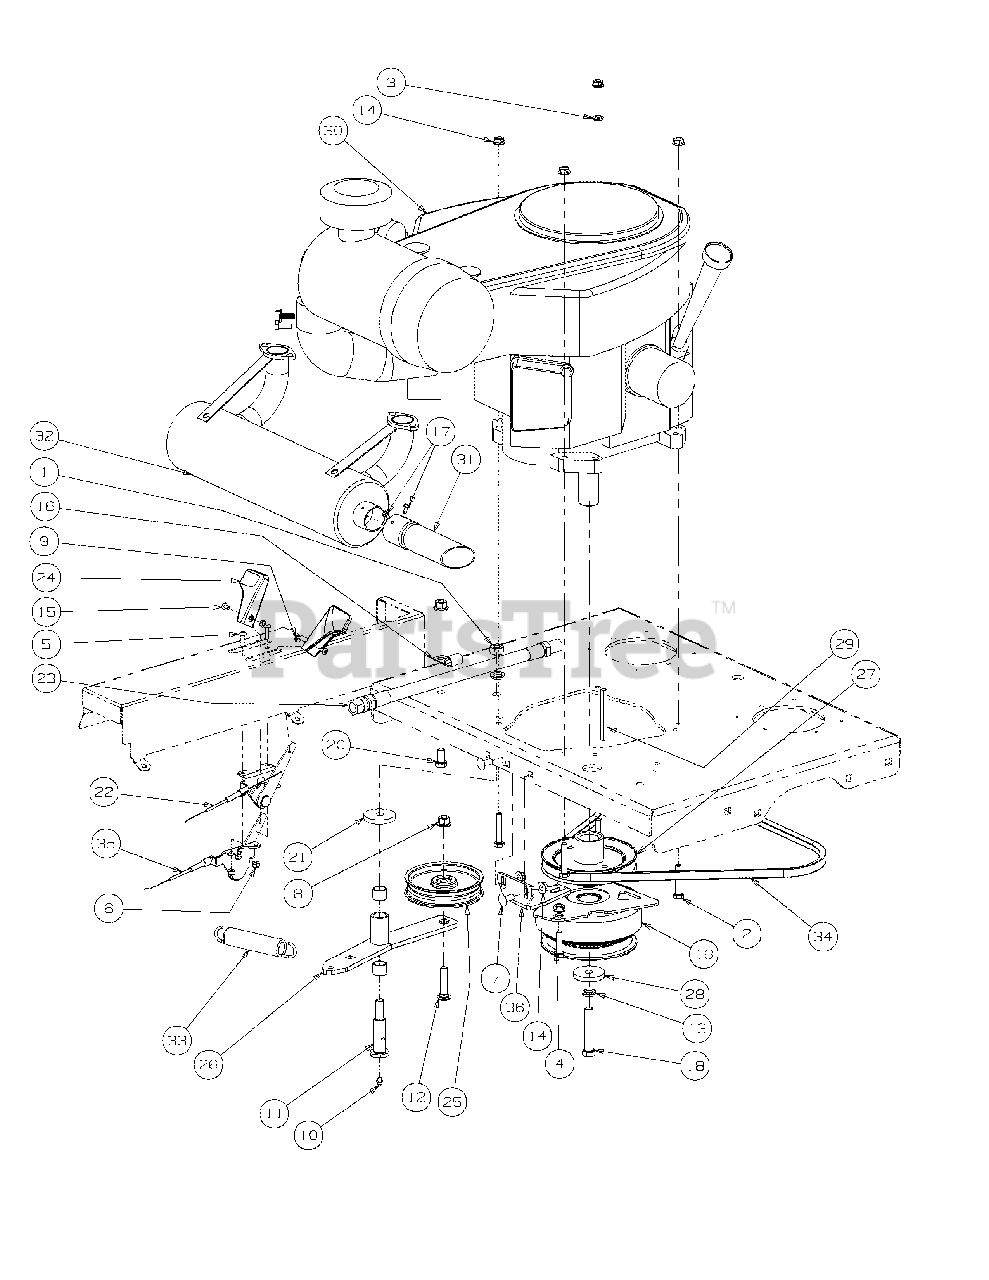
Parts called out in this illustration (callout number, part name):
1	Hex Nut, 7/16-14
2	HHCS, 5/16-18, 1-3/4
3	Flat Washer, .320 ID x .591 OD x .078
4	HHCS, 5/16-18 x 1-1/4
5	Round Hd. Machine Screw, 10-32 x 3/4
6	Lock Nut, Nylon Insert, 10-32
7	Carriage Bolt, 5/16-18 x .75
8	Flange Lock, Hex Nut, 3/8-16
9	Nut Washer, W/Star, 8-32
10	Grease Fitting, 1/4-28 x 3/16
11	Shoulder Screw, 7/16-14
12	Hex Carriage Screw, 3/8-16, 1.75
13	Lock Washer, 7/16
14	Hexflange Lock Nut, 5/16-18
15	Machine Screw, 8-32, .375
16	Clip, Heat Shield Cable
17	Screw, #8-32 x 0.375
18	Capscrew, 7/16-20 x 2.50
19	Clutch Brake, 1.125 ID
20	Hex Cap Screw, 3/8-16, .750
21	Flat Washer, 7/16 ID x 1.75 OD x .25
22	Choke, Control Cable, 43.0
23	Oil Drain Hose
24	Control Throttle Knob
25	Flat Pulley with Flanges
26	Engine Idler Arm Assembly Includes
27	Pump Drive Pulley
28	Flat Washer, 7/16 ID x 1.75 OD x .25
29	Key, 1/4 x 1/4 x 3
30	23HP Engine, Kawasaki
31	Muffler Accessory Exhaust Tube
32	Muffler Accessory, Kawasaki
33	Extension Spring, .98 OD x 5.00
34	V Belt, A Section x .48.5
35	Throttle, Control Cable, 39.0
36	Retainer Clutch Assembly, Ogura
